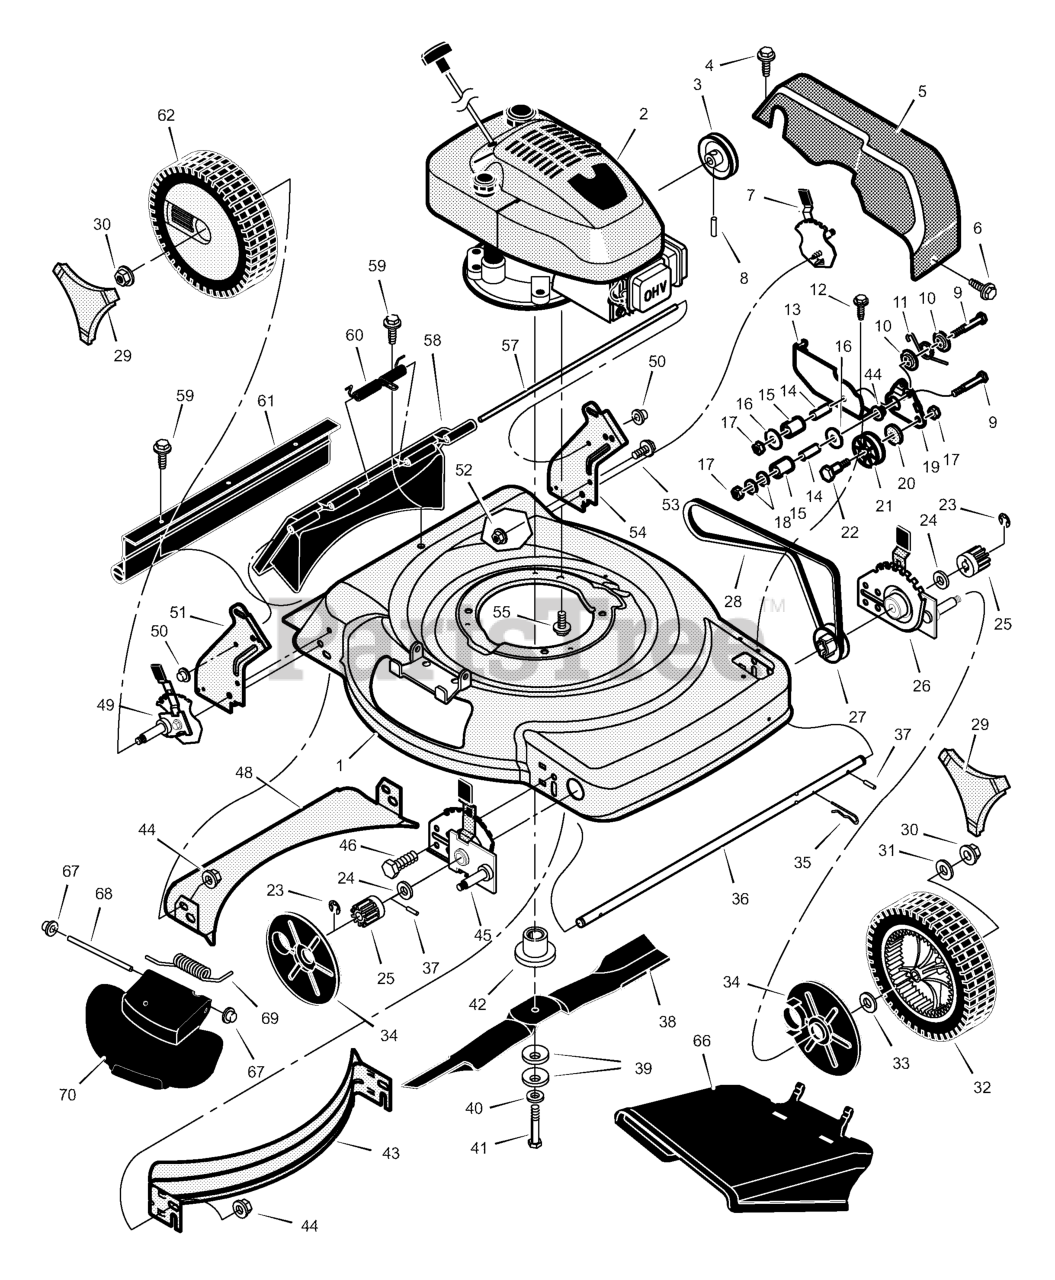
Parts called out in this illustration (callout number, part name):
1	Housing
2	Engine *
3	Pulley, Drive
5	Cover, Belt (Gray)
7	Adjuster, Left Rear Height
8	Pin, Spring
10	Spacer, Idler Arm
12	Screw
13	Bracket, Idler Support
14	Bearing, Idler
15	Pulley, Idler
17	Nut
18	Washer
19	Arm, Pivot
20	Spacer, Idler
21	Pulley, Idler
22	Bolt, Shoulder
25	Gear, Pinion
26	Adjuster, Left Front Height
27	Pulley, Axle
29	Cap, Hub
30	Nut, Flange
31	Washer
32	Wheel & Tire, Front
34	Cover, Dust
35	Pin, Hair
37	Pin, Drive
39	Washer, Belleville
42	Adapter, Blade
43	Baffle, Front
44	Nut, Flange
45	Adjuster, Right Front Height
46	Bolt
48	Baffle, Rear
49	Adjuster, Right Rear Height
50	Push On Cap
51	Bracket, Right Handle
52	Nut, Flange
53	Bolt
54	Bracket, Left Handle
55	Bolt, Engine
57	Rod, Pivot
58	Door, Rear (Gray)
61	Guard, Rear
62	Wheel & Tire, Rear
66	Deflector, Chute
67	Push On Cap
68	Rod, Pivot
69	Spring, Torsion
70	Cover, Mulch (Gray)
